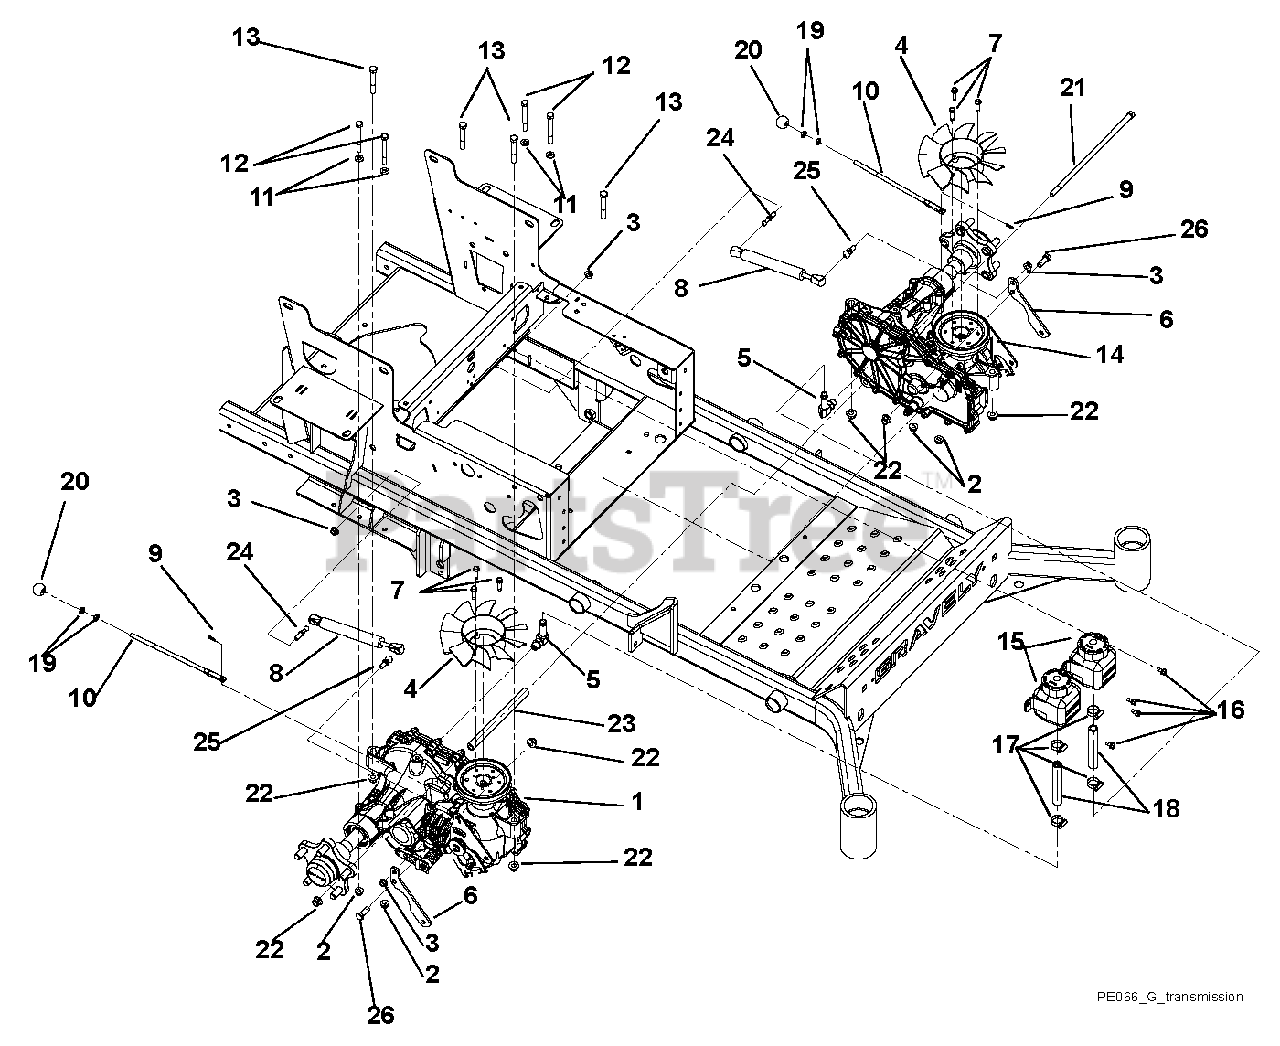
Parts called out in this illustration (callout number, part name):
1	Transaxle, 100I – Right Hand
2	Nut, .31-18 Nyloc Flange
3	Nut, Locking Top Flange .31-18
4	Fan, 2800 Series Cooling
5	Fitting, Hydraulic (90 DEG)
6	Transmission Damper Mounting Plate
7	Screw, Tapping .25-20 x 1.00 Hex Washer Head Thread Rolling
8	Damper
9	Pin, Hair, Internal .06 x .18 x .77
10	Lever, 100I Dump Valve
11	Washer, Flat Steel .344 x .688 x .065
12	Bolt, Hex .31-18 x 3.00
13	Bolt, Hex .38-16 x 2.50
14	Transaxle, 100I – Left Hand
15	Tank, Expansion ZT2800
16	Screw, Tapping .25-20 x .50 Hex Washer Head Thread
17	Clamp, .88 Diameter Hose
18	Hose, 100I Hydro Overflow
19	Nut, Jam .312-18 UNC YWZC
20	Knob, Ball Black .312-18 x 1.00
21	Bolt, Hex .38-16 x 11.00
22	Nut, Locking-Nylon-Flange .38-16
23	Spacer, .38 ID x 5/8 OD x 7.72
24	Stud, Ball, Threaded
25	Stud, Ball
26	Bolt, Hex .38-16 x 1.00
NS	Oil Filter, 2800 Transmission
